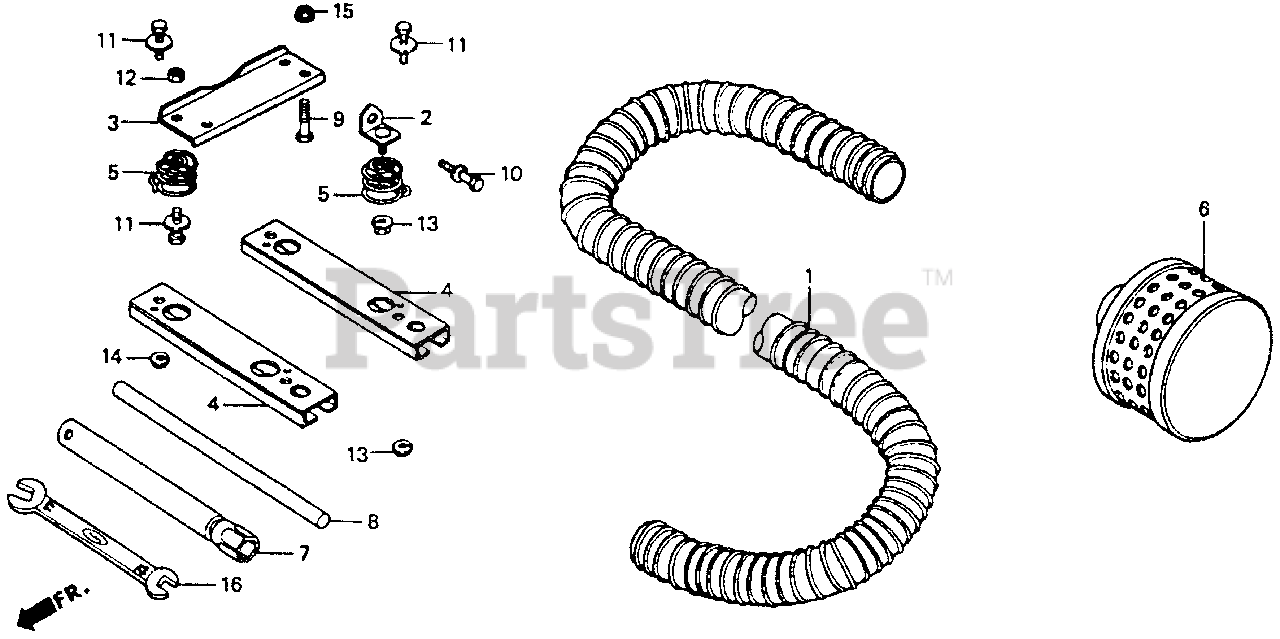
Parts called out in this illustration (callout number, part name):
1	HOSE, SUCTION
2	STAY, MOUNT
3	BRACKET, ENGINE
4	BED, FRAME
5	SPRING, MOUNT
6	STRAINER (NOT AVAILABLE)
7	WRENCH, SPARK PLUG
8	HANDLE, BOX WRENCH
9	BOLT, HEX. (8X32)
10	BOLT-WASHER (8X40)
11	BOLT-WASHER (8X20)
12	NUT, HEX. (8MM)
13	NUT, FLANGE (8MM)
14	NUT-WASHER (8MM)
15	NUT-WASHER (8MM)
16	SPANNER (12X17) (NOT AVAILABLE)
